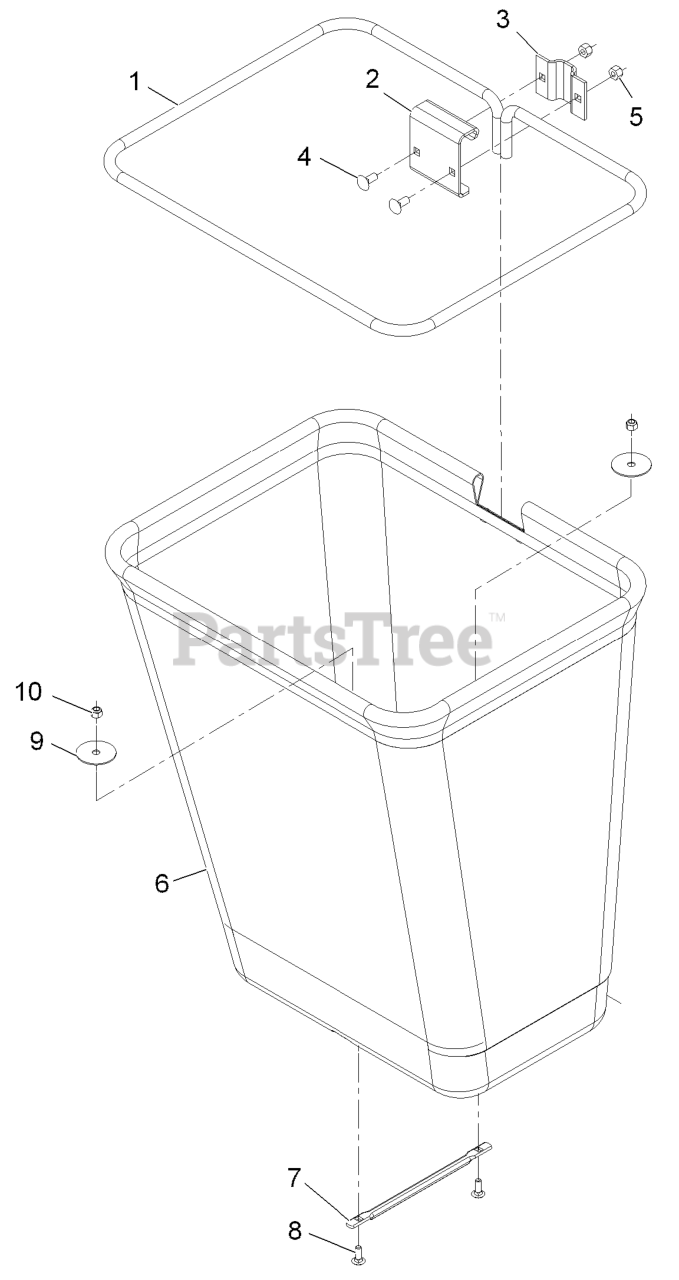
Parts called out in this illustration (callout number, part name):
1	Frame-Bag
2	Hanger-Bag
4	Bolt-Carriage 5/16-18 X 3/4
5	Nut-Nyloc 5/16-18
6	Bag ASM
7	Handle-Bag
8	Bolt-Carriage 1/4-20 X 3/4
10	Nut-Nyloc 1/4-20
